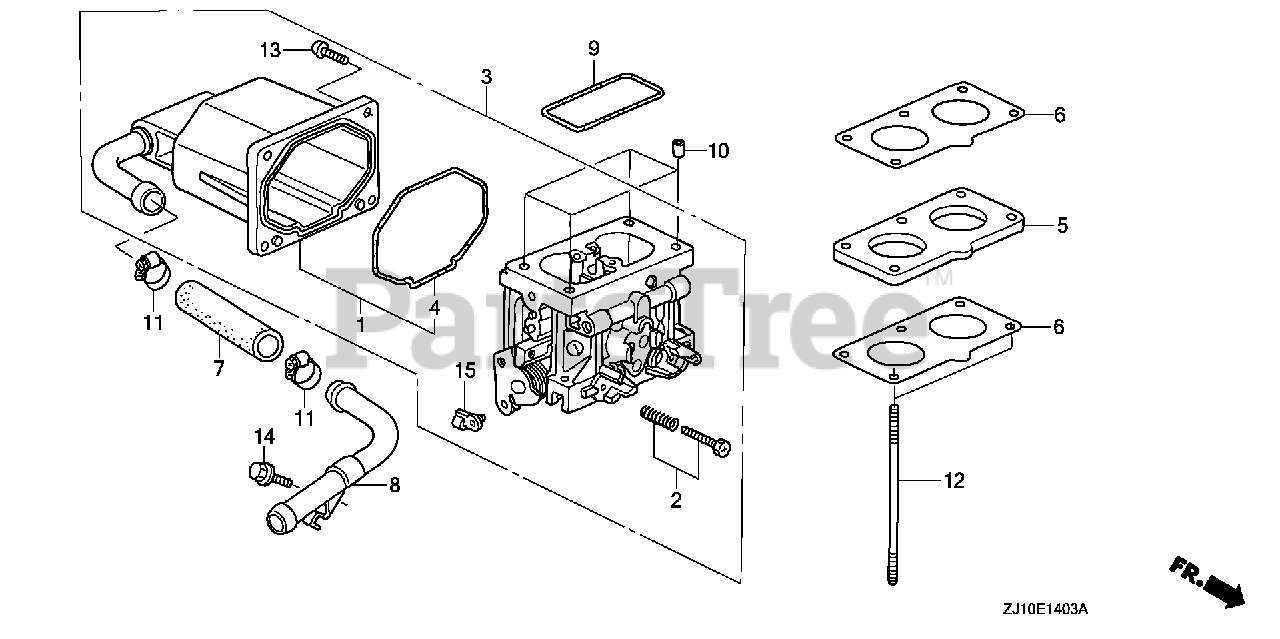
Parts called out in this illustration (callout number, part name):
1	CHAMBER SET, FLOAT
2	SCREW SET, THROTTLE
3	CARBURETOR ASSY. (BKL0A A)
4	GASKET, FLOAT CHAMBER
5	INSULATOR, CARBURETOR
6	GASKET, CARBURETOR
7	HOSE, FUEL
8	JOINT, FUEL
9	GASKET, AIR CLEANER
10	COLLAR A, AIR CLEANER
11	CLAMP, WATER HOSE
12	BOLT, STUD (6X108)
13	SCREW, PAN (4X14)
14	BOLT, FLANGE (8X20)
15	ARM, THROTTLE LINKAGE
